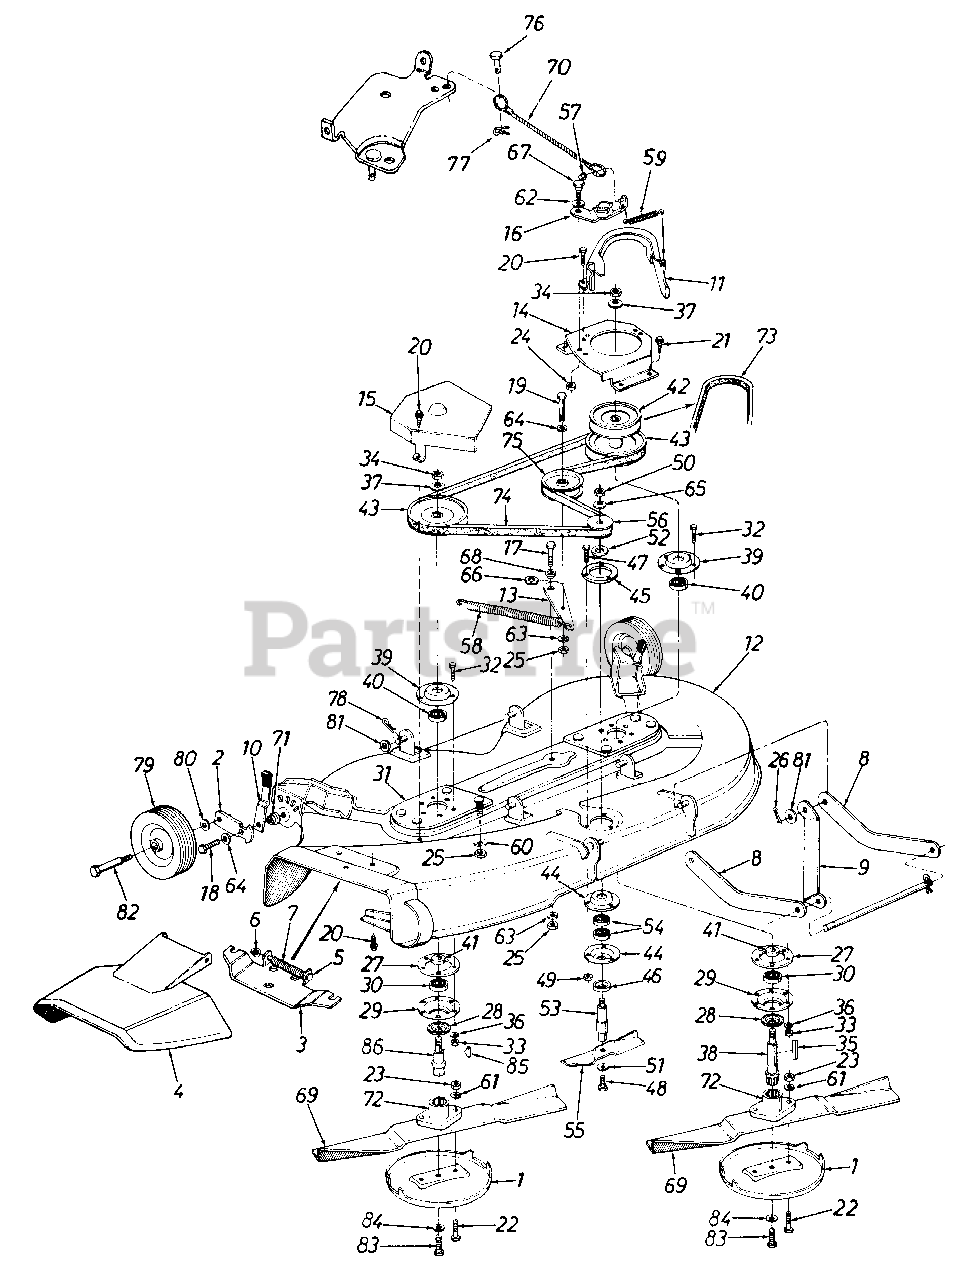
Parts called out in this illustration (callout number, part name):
1	Anti-Scalp Plate
2	Wheel Pivot Bar
3	Adapter
4	Chute Cover Ass'y.
5	Hinge Pin
6	Cap Speed Nut 1/4" Rod.
7	Torsion Spring
11	Belt Guard
12	44" Deck Ass'y.
13	Idler Bracket
14	Pulley Cover L.H.
17	Hex Bolt 3/8-24 x 1.00"*
18	Hex Bolt 3/8-24 x 1.25" Lg.
19	Hex Bolt 3/8-24 x 1.50"*
20	Hex Wash. S-Tapp Scr. 1/4-20 x .50"
21	Hex Wash. Hd. Tapp Scr. 5/16-18 x .75" Lg.
22	Hex Bolt 5/16-24 x 1.0" Lg.
23	Hex Nut 5/16-24 Thd.*
24	Hex Cent. L.-Nut 5/16-18 Thd.
25	Hex Nut 3/8-24 Thd.*
26	Cotter Pin 3/32 Dia. x 1.00" Lg.*
27	Reinforcement Plate
28	Bearing Shield
29	Open Brg. Housing 1.85 I.D.
30	Ball Brg. .787 I.D. x 1.85 O.D. x .551
31	Spindle Mounting Plate Ass'y.
32	Hex Bolt 5/16-24 x 1.0" Lg.
33	Hex Nut-5/16-24
34	Hex Jam Nut 5/8-18 Thd.
35	Square Key 3/16 x 2. 25" Lg.
36	L.-Wash. 5/16 I.D.*
37	Bell. Wash. .630 I.D. x 1.25 x .090
38	44" Deck Blade Spindle
39	Bearing Housing 1.85 I.D.
40	Ball. Brg. .787 I.D. x 1.85 O.D. x .551
41	Spacer 1.0 O.D. x .790 I.D. .350 Lg
42	5/8 "V"-Pulley .79 I.D. x 5.75 O.D.
43	"V"-Pulley .79 I.D. x 6. 50 O.D.
44	1-3/8" I.D.-Bearing Housing
45	Reinforcement Plate
46	Bearing Shield
47	Hex Bolt 1/4-20 x .62" Lg.*
48	Hex Cl.-Scr. 3/8-24 x .88 Lg.
49	Hex Nut 1/4-28 Thd.
50	Hex Jam Nut 1/2-20 Thd.
51	Bell.-Wash. .400 I.D. x .88 O.D. x .060
52	FI.-Wash. .635 x 1.04 O.D. x .120"
53	6.5" Blade Spindle
54	Ball Brg. .62 I.D. x 1.30" O.D. x .44"
55	6.50" Blade
56	1/2" V-Pulley Half .625 I.D. x 2.25" O.D.
57	Cap Speed Nut 1/4" Rod.
58	Extension Spring .73 O.D. x 4.31 Lg.
59	Extension Spring .38 x 2.75" Lg.
60	Bell.-Wash. .400 I.D. x .88 O.D. x .060
61	L.-Wash. 5/16" I.D.*
62	Spring Wash. .445 I.D. x .75 O.D. x .017
63	L.-Wash. 3/8" I.D.*
64	Bell.-Wash. .400 I.D. x 1.13 O.D. x .030
65	Bell.-Wash. .505 I.D. x 1.00 O.D. x .075
66	Spring Wash. .650 I.D. x .875 O.D. x .015 Thk.
67	Shld. Bolt .437 Dia. x .180
68	Shld. Spacer .625 I.D.
69	Mower Blade 21.88
70	Brake Cable Ass'y.
71	Shld. Spacer
72	Blade Adapter
73	"V"-Belt 1/2 x 56" Lg.
74	"V"-Belt 1/2 x 74" Lg.
75	Fl.-Idler w/Flanges 3.50 O.D.
76	Clevis Pin 1/4 Dia. x .53 Lg.
77	Intern. Cotter Pin 5/16" Dia.
78	Intern. Cotter Pin 1/2" Dia.
79	Deck Wheel 6.0 x 1.38
80	Bell.-Wash. .400 I.D. x .88 O.D. x .060
81	Fl.-Wash. .531 I.D. x .93 O.D. x .090
82	Shoulder Bolt 3/8-16 x 1.41
83	Hex Bolt 3/8-24 x .88" Lg.
84	L.-Washer 3/8 Heavy Duty
85	Sq. Key 3/16 x .75" Lg.
86	44" Deck Blade Spindle
